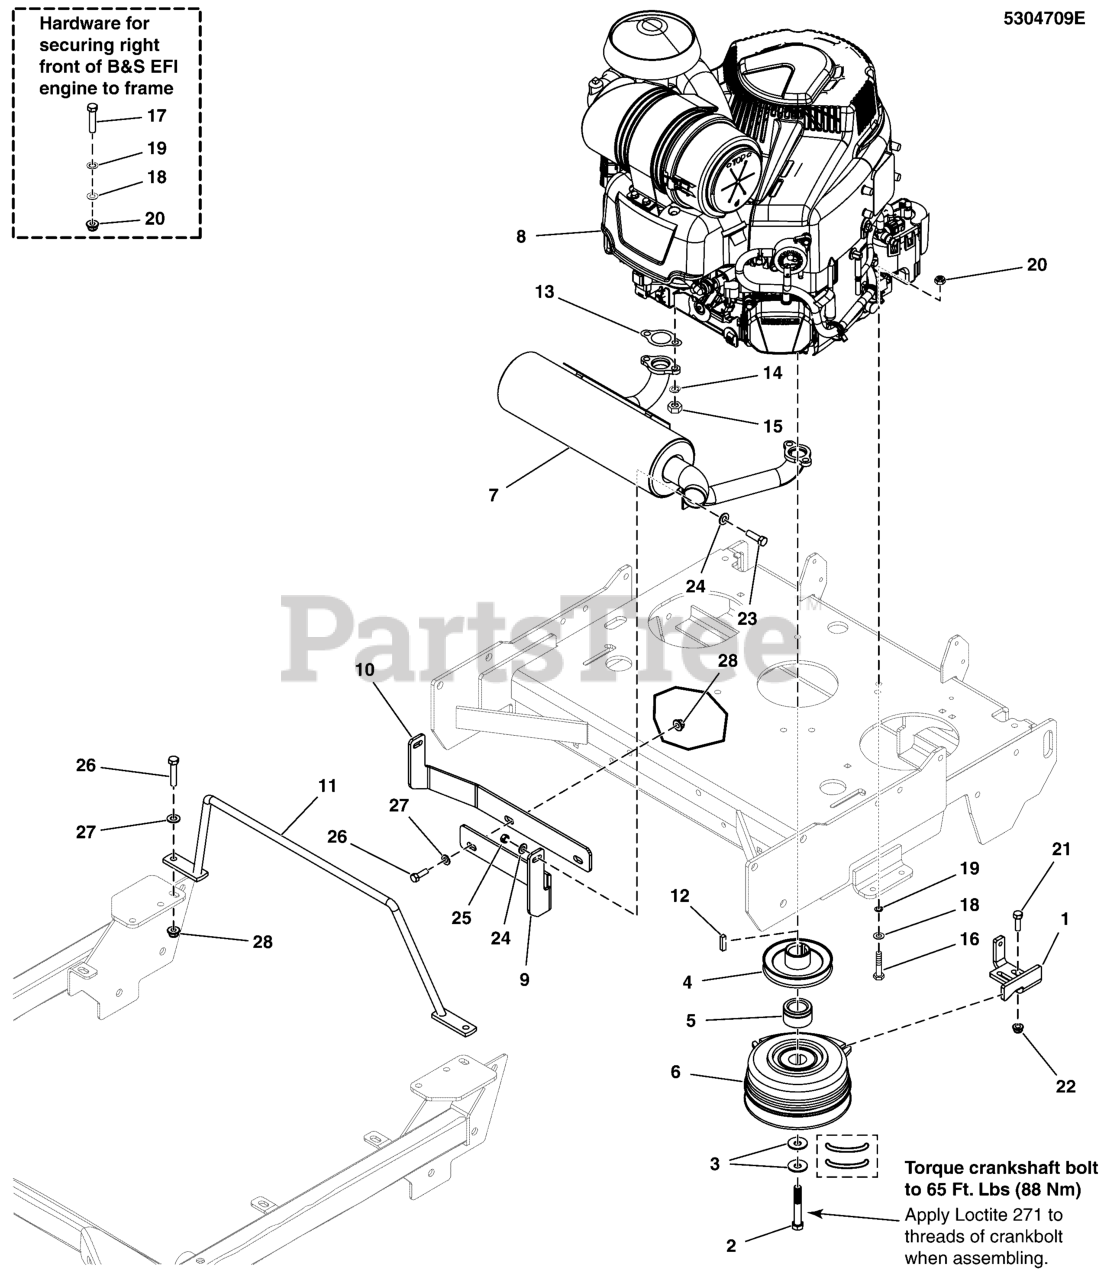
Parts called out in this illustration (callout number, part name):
1	PLATE, CLUTCH ANCHOR - BLK
2	BOLT, CRANKSHAFT,7/16-20X2-3/4, GD8
3	BELLEVILLE WASHER 1.1875 X .442 X .089
4	PULLEY, CRANKSHAFT, 1.125ID X 4.50OD, OS
5	SPACER, 1.13 X 1.75 X 1.03, CZ
6	CLUTCH,WARNER,200 'lbs,1.13
7	MUFFLER, 26/28, B&S VANG, EFI TWR/WALK
9	PLATE, MUFFLER SUPPORT, LH, W35 - BLK
10	PLATE, MUFFLER SUPPORT, RH, W35 - BLK
11	WELD, MUFFLER/02, GUARD, W45 - BLK
12	KEY, 1/4 SQ X 1
13	GASKET, EXHAUST
14	WASHER, 5/16 LIGHT LOCK
15	NUT, 5/16-18 HEX
16	BOLT, 5/16-24 X 1-3/4, GD8, PHOS
17	BOLT, 5/16-24 X 1-1/2, GD8, PHOS
18	WASHER, 5/16" SAE
19	WASHER, 5/16 INT. TOOTH LOCK
20	NUT, 5/16-24, TOP LOCK FLANGE, GD8 PHOS
21	BOLT, 5/16-18 X 1, CARRIAGE
22	NUT, 5/16-18 HEX NYLOCK FLANGE
23	BOLT, 5/16-18 X 1 GD5 CZ
24	WASHER, 5/16 F436 FLAT
25	NUT, 5/16-18, HEX, CNTR LK,ZINC PHOS/OIL
26	BOLT, 3/8-16 X 1-1/4" GD5 CZ
27	WASHER, 3/8 SAE
28	NUT, 3/8-16 HEX NYLOCK FLANGE
